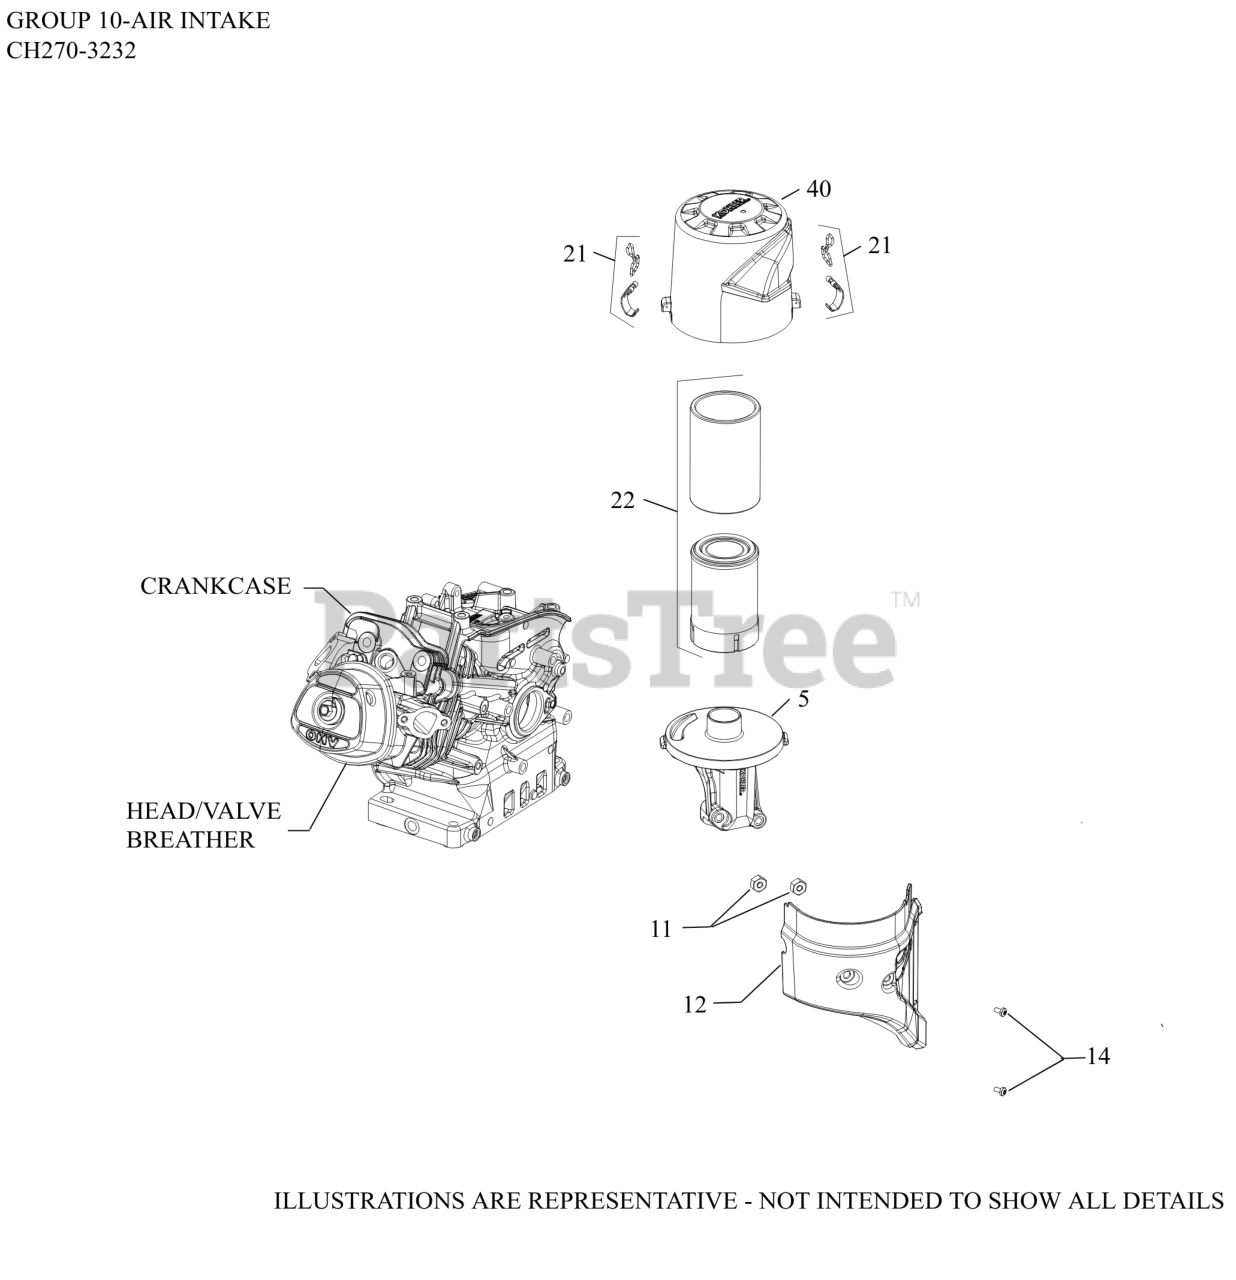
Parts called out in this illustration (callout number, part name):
1	COVER, AIR CLEANER ASSEMBLY
5	KIT, AIR CLEANER BASE ASSEMBLY
11	NUT, HEX (M6 THREAD, M8 BODY)
12	COVER, AIR CLEANER BASE SHIELD
14	SCREW,COVR TO BLWR HOUSING
21	KIT, LATCH CLIP
22	ELEMENT, AIR FILTER
